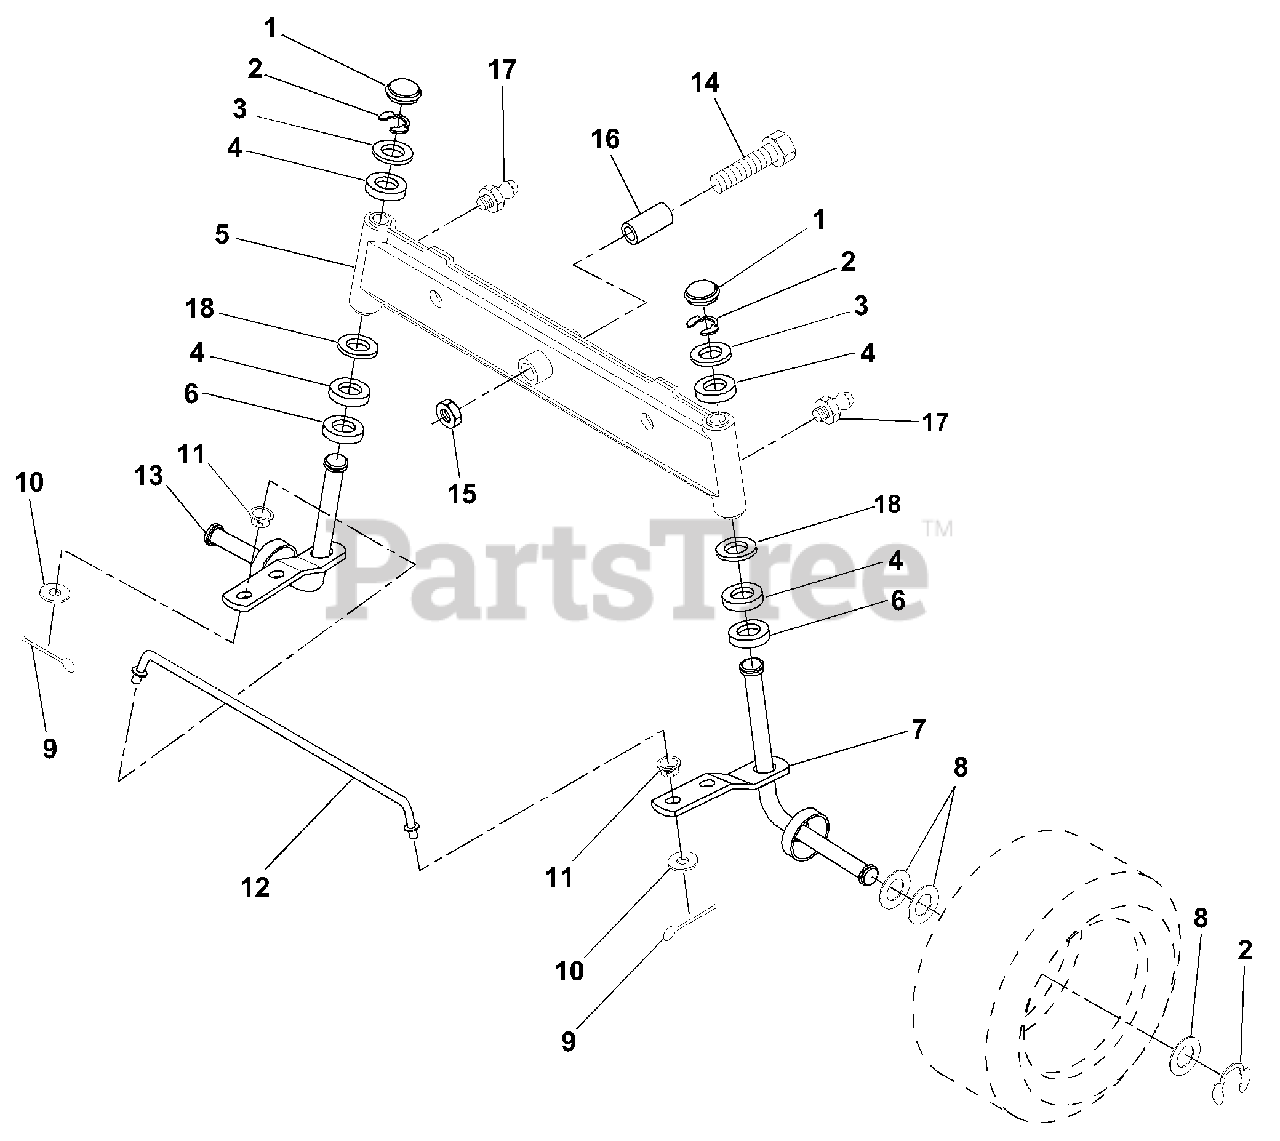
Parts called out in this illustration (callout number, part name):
1	Cap, Spindle
2	Ring, Clip
3	Washer 25/32 x 1-5/8 x 16 Gauge
4	Bearing
5	Axle, Front
6	Bearing, Thrust
7	Spindle Assembly, R.H.
8	Washer 25/32 x 1-1/4 x 16 Gauge
9	Pin, Cotter 1/8 x 3/4
10	Washer 13/32 x 13/16 x 16 Gauge
12	Tie Rod
13	Spindle Assembly, L.H.
14	Bolt Hex 5/8-11 Unc x 3-1/2
15	Nut Lock Flange 5/8-11 Unc
16	Spacer Bearing
17	Fitting Grease
18	Washer 27/32 x 1-1/4 x 16 Ga.
